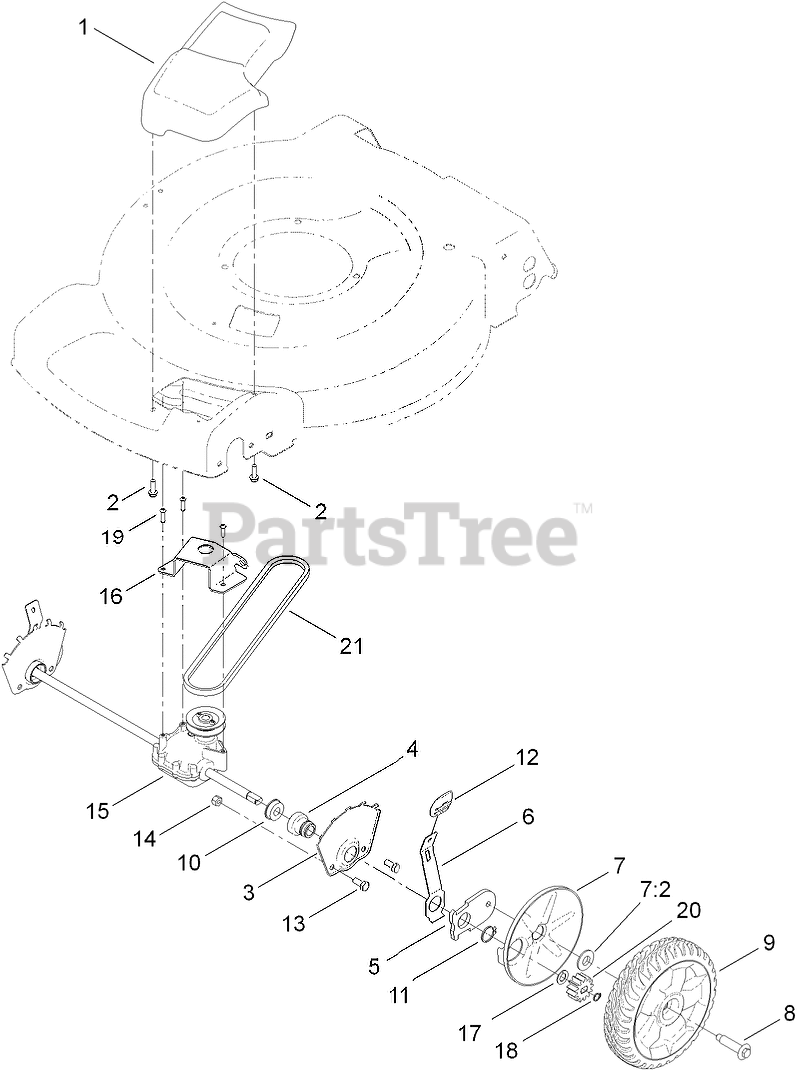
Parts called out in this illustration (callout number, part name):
1	COVER-BELT
2	SCREW-HWH
3	PLATE-HOC, FRONT
4	RETAINER-BEARING, HOC
5	ARM-PIVOT, FRONT
6	Arm-Spring
7	WHEEL COVER ASM
7:2	WASHER-STEPPED
8	BOLT-SHOULDER
9	8 INCH WHEEL ASM
10	BEARING-BALL
11	RING-RETAINING
12	Knob-Lever, HOC
13	SCREW-HH
14	NUT-LOCK, NI
15	TRANSMISSION ASM
16	BRACKET-TRANSMISSION
17	WASHER-THRUST
18	RING-RETAINING
19	SCREW-PAN HEAD, T20
20	GEAR-PINION, 13T
21	V-BELT
